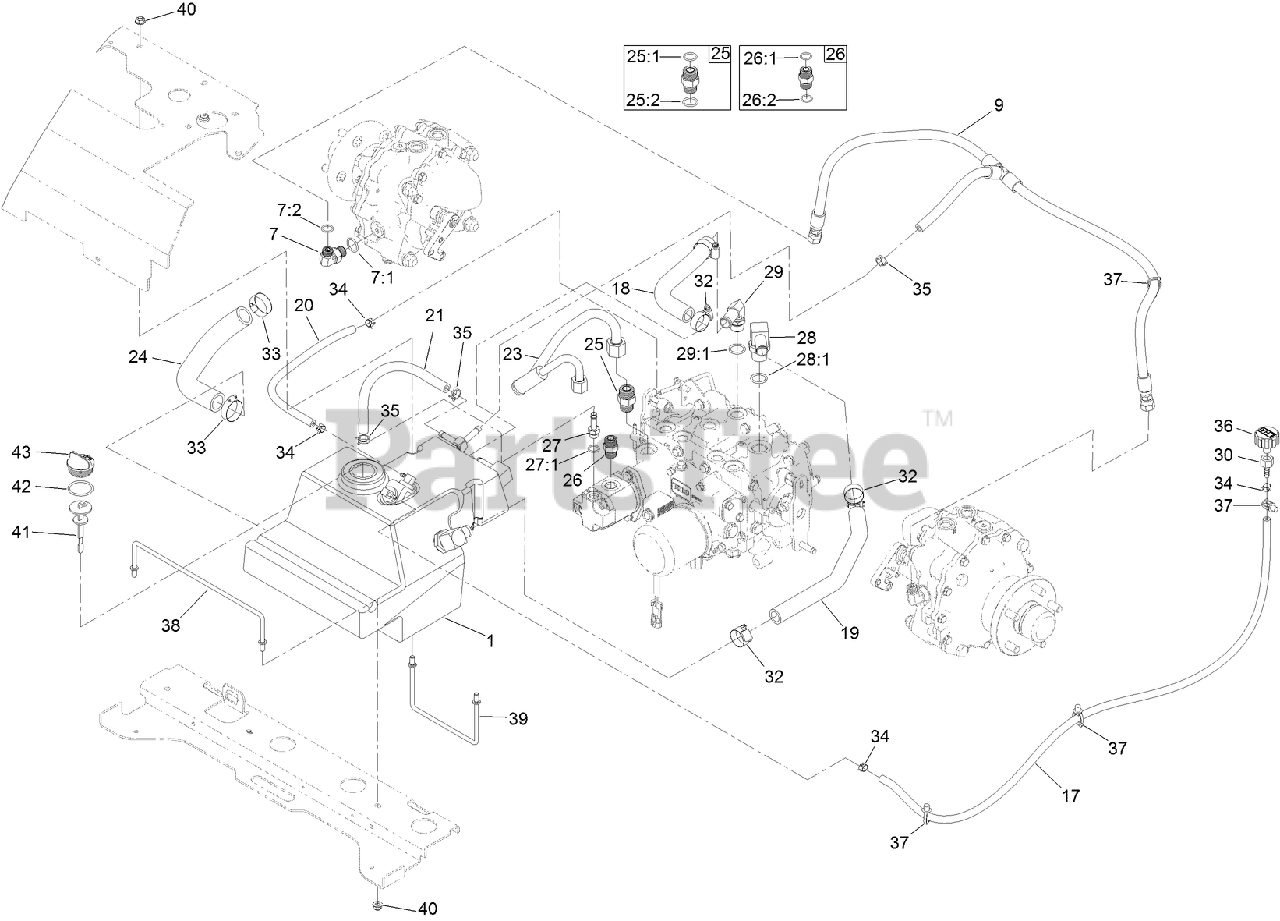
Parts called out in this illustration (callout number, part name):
1	HYD RESERVOIR ASM
7	FITTING-HYD, 90 DEG
7:1	O-RING
7:2	O-RING
9	HOSE ASM
18	HOSE-RETURN
19	HOSE-RETURN
23	TUBE ASM
24	HOSE-SUCTION
25	FITTING-STRAIGHT
25:1	O-RING
25:2	O-RING
26	FITTING-STRAIGHT
26:1	O-RING
26:2	O-RING
27	ADAPTER-STRAIGHT
27:1	O-RING
28	FITTING-ELBOW, 90
28:1	O-RING
29	FITTING-90
29:1	O-RING
30	FITTING-STRAIGHT
32	CLAMP-HOSE
33	CLAMP-HOSE
34	CLAMP-HOSE
35	CLAMP-HOSE
36	BREATHER
37	CLIP-TIE
38	ROD-SUPPORT, HYD TANK
39	ROD-SUPPORT, HYD TANK
40	NUT-HF, NI
41	DIPSTICK
42	O-RING
43	PLUG-PLASTIC
